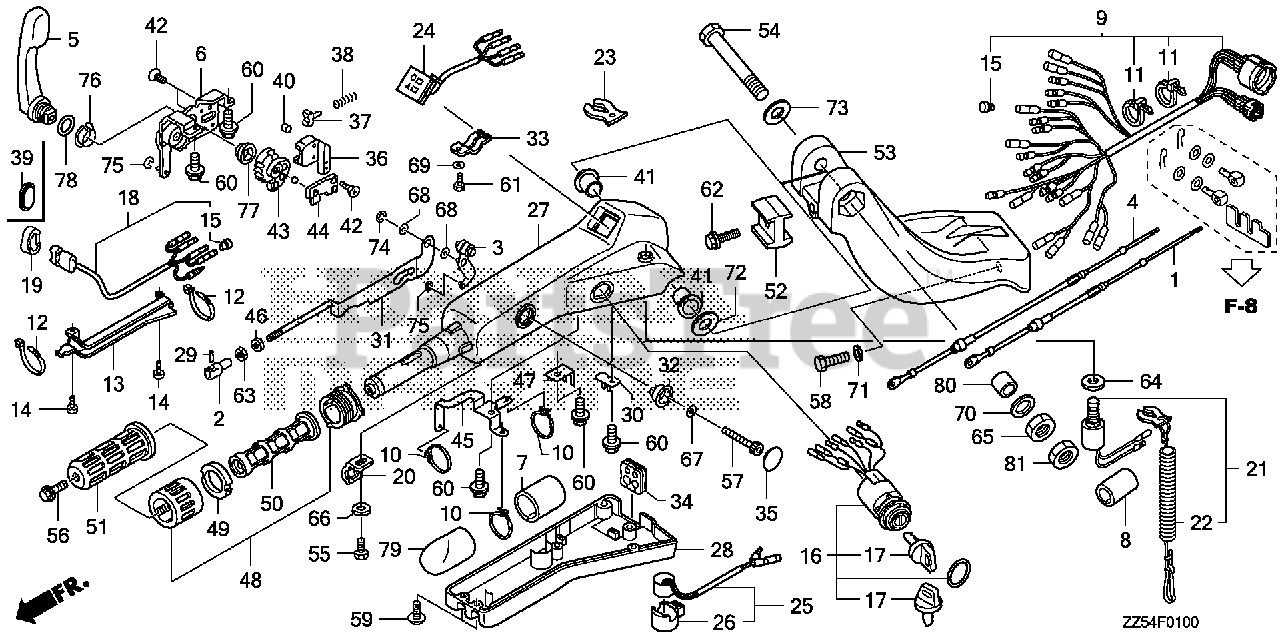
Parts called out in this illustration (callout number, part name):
1	CABLE, THROTTLE
2	PIVOT, THROTTLE CABLE
3	ARM, THROTTLE
4	CABLE, SHIFT
5	LEVER, SHIFT
6	FRAME ASSY., SHIFT
7	TUBE (38.1X40)
9	CABLE ASSY., LONG HANDLE (A)
10	BAND (CONVEX CV-150)
11	BAND (CONVEX CV-200)
12	BAND (CONVEX)
13	COVER, WIRE
15	PLUG, CONNECTOR (INNER) (TROLLING CONTROL)
16	SWITCH ASSY., COMBINATION
17	KEY ASSY., COMBINATION SWITCH (35100-ZV5-003 ONLY) DUAL QTY = (4) (SINGLE)
20	HOLDER, SWITCH
21	SWITCH ASSY., EMERGENCY STOP
22	WIRE, EMERGENCY (SINGLE) (DUAL)
23	CLIP, EMERGENCY LOCK
24	LAMP ASSY., INDICATOR
25	BUZZER ASSY., WARNING
26	SUSPENSION, WARNING BUZZER
27	HOUSING *NH282MU* (OYSTER SILVER METALLIC-U)
28	COVER, HANDLEBAR (LOWER)
29	PIN, THROTTLE CABLE
30	BRACKET, CABLE
31	PLATE ASSY., LOCK
33	PLATE, GUIDE
36	GUIDE, SPRING
38	SPRING, COIL
39	GROMMET, POWER TILT SWITCH
41	BUSH, HANDLEBAR
42	SCREW (M5X14)
43	GEAR, SHIFT
44	PLATE, BALL GUIDE
46	ROD, GROMMET
47	CLAMP, BRACKET
48	GRIP ASSY., THROTTLE FRICTION
49	PAD, THROTTLE FRICTION
50	PIPE, GRIP
51	RUBBER, GRIP
52	BLOCK, HEIGHT ADJUSTER
53	BRACKET, STEERING *NH282MU* (OYSTER SILVER METALLIC-U)
54	BOLT, HEX. (12X80)
55	BOLT (M5X8)
56	BOLT, FLANGE (6X12) Use from Frame SN 1005249.
57	BOLT (M8X50)
58	BOLT, HEX. (10X32)
59	BOLT (M5X12)
60	BOLT (M6X12)
61	BOLT (M5X12)
62	BOLT, FLANGE (8X28)
63	NUT, HEX. (5MM)
64	NUT, HEX. (16MM) DUAL QTY = (2) (SINGLE)
65	NUT, HEX. (12MM)
66	WASHER (5MM)
67	WASHER (8MM)
68	WASHER (10MM)
69	WASHER (5MM)
70	WASHER, WAVE (14MM)
71	WASHER (10MM)
72	WASHER, PLAIN (12MM)
73	WASHER, PLAIN (12MM)
78	O-RING (20.6X1.9)
79	TUBE, CORD (40MM)
80	COLLAR, DISTANCE (12.2X23X16)
81	NUT, HEX. (12MM)
